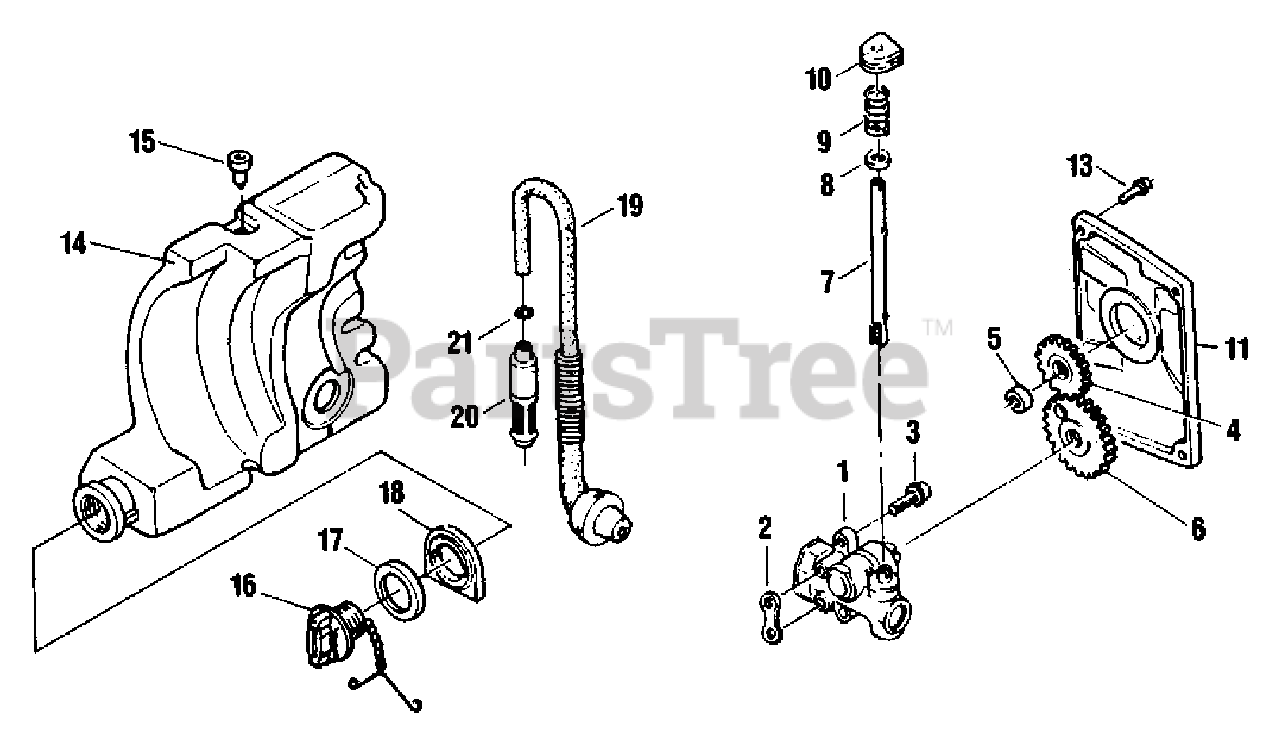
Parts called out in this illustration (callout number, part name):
1	OIL PUMP ASSY
2	GASKET, OIL PUMP
3	SCREW
4	PINION
6	GEAR
7	SHAFT, OIL PUMP
8	WASHER 4 MM
11	COVER, PUMP
13	SCREW
14	TANK, OIL
15	VENT ASSY
16	CAP, OIL
17	GASKET, CAP
18	TANK, OIL
20	OIL FILTER
21	CLIP, OIL FILTER
